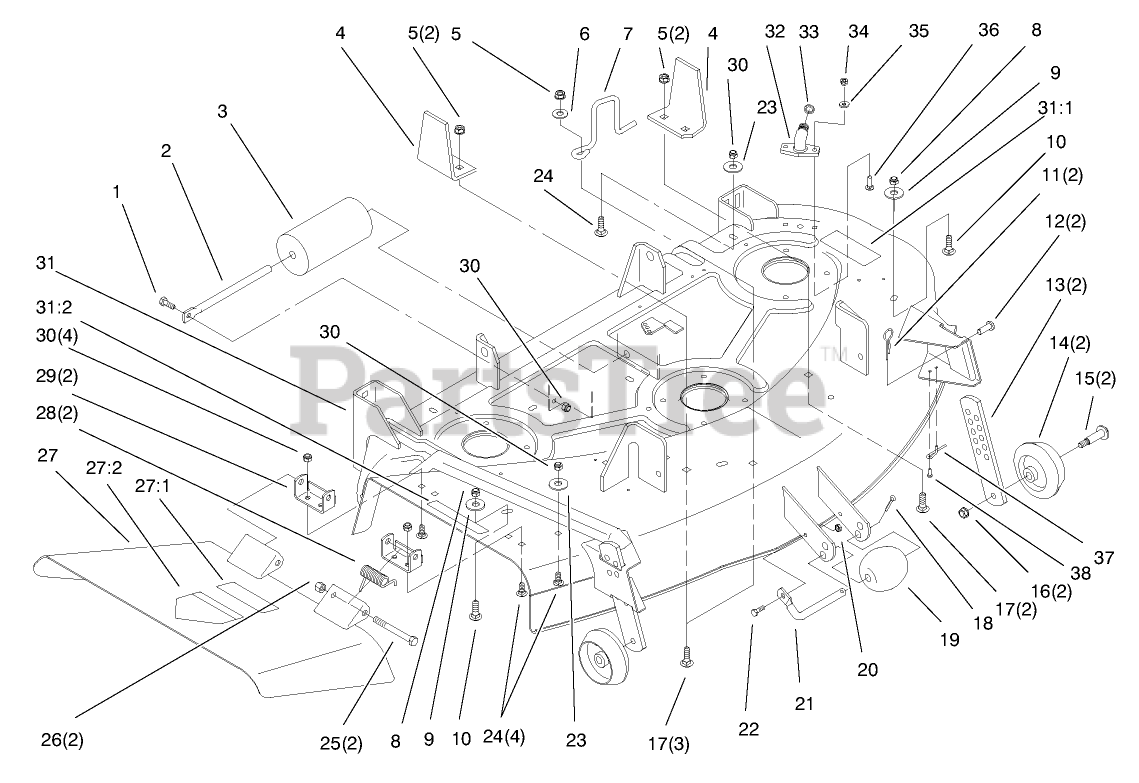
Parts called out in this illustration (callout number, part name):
1	SCREW-HH
2	ROD-ROLLER
3	ROLLER-DECK
5	NUT-LOCK, NI
6	WASHER
8	NUT-LOCK, NI
9	WASHER-FLAT
10	SCREW-CARR
11	PIN-HAIR
12	PIN-CLEVIS
13	PLATE-GAGE WHEEL
14	WHEEL-GAGE
15	SCREW-SHOULDER, HWH
17	BOLT-CARR
18	PIN-COTTER
19	ROLLER
20	NUT-LOCK, NI
22	SCREW-HH
23	WASHER-FLAT
24	SCREW-CARR
25	SCREW-HH
26	NUT-HEX
27	Deflector ASM (Only On: 78357, 78358)
27	Deflector ASM (Only On: 78444)
27:1	DECAL-DANGER
27:2	DECAL-DANGER
28	SPRING
29	BRACKET-PIVOT
30	NUT-LOCK, NI
31:1	DECAL-CAUTION
31:1	DECAL-DANGER
31:2	DECAL-DANGER
32	NUT-LOCK, NI
33	WASHER-FLAT
35	O-RING
36	BOLT-CARR
37	SPRING-GAGE WHEEL
38	SCREW-HWHTF
